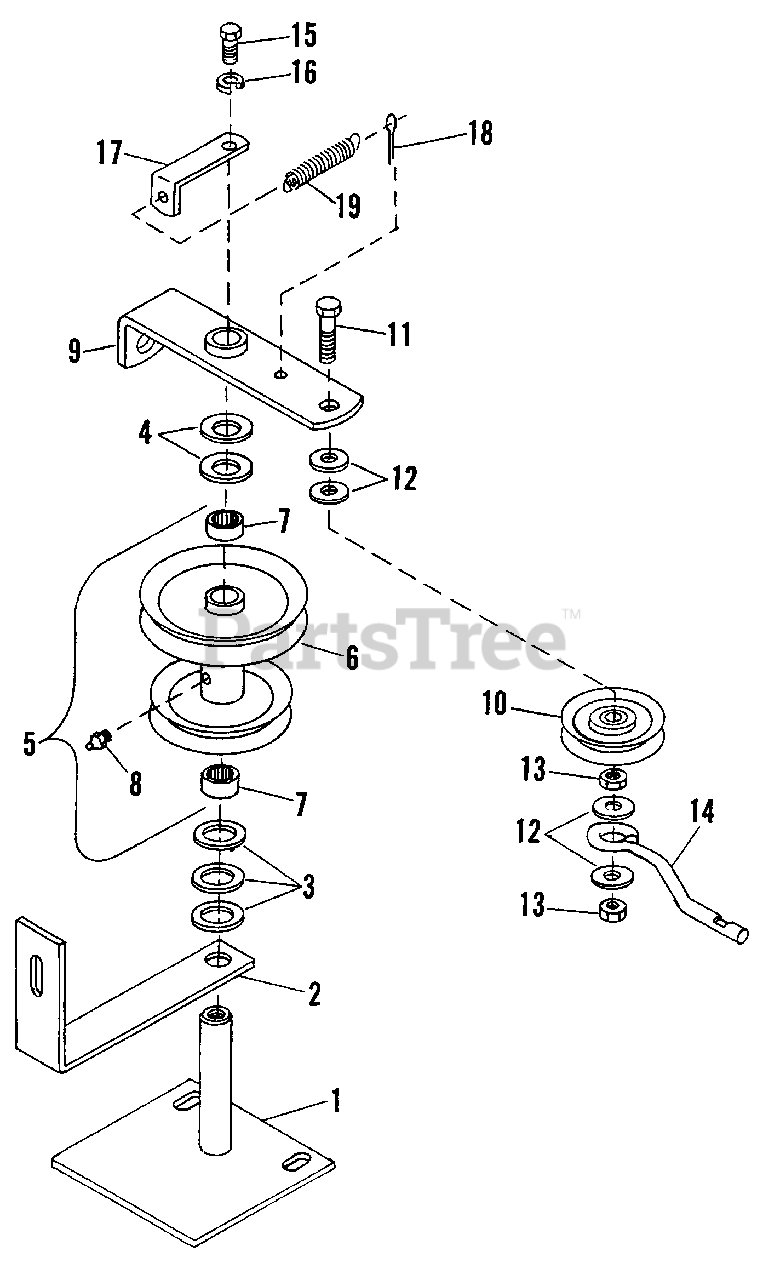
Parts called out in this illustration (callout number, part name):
1	Pulley Mounting Bracket Assembly
2	Belt Adjustment Bracket
3	Washer - 13/16" x 1 1/2" x .134 Flat
5	Pulley Housing Assembly (Complete)
6	Pulley Housing Assembly
7	Needle Bearing
8	Grease Fitting
9	Idler Arm Assembly
10	Idler Pulley
11	Bolt - 3/8-16 x 2 1/2" Hex Head
12	Washer - 7/16" x 1" x .083 Flat
13	Nut - 3/8-16 Hex Lock
14	Belt Gauge Wire
15	Bolt - 3/8-16 x 3/4" Hex Head
16	Washer - 3/8" Medium Lock
17	Spring Anchor Bracket
18	Spring Anchor Pin
19	Idler Release Spring
